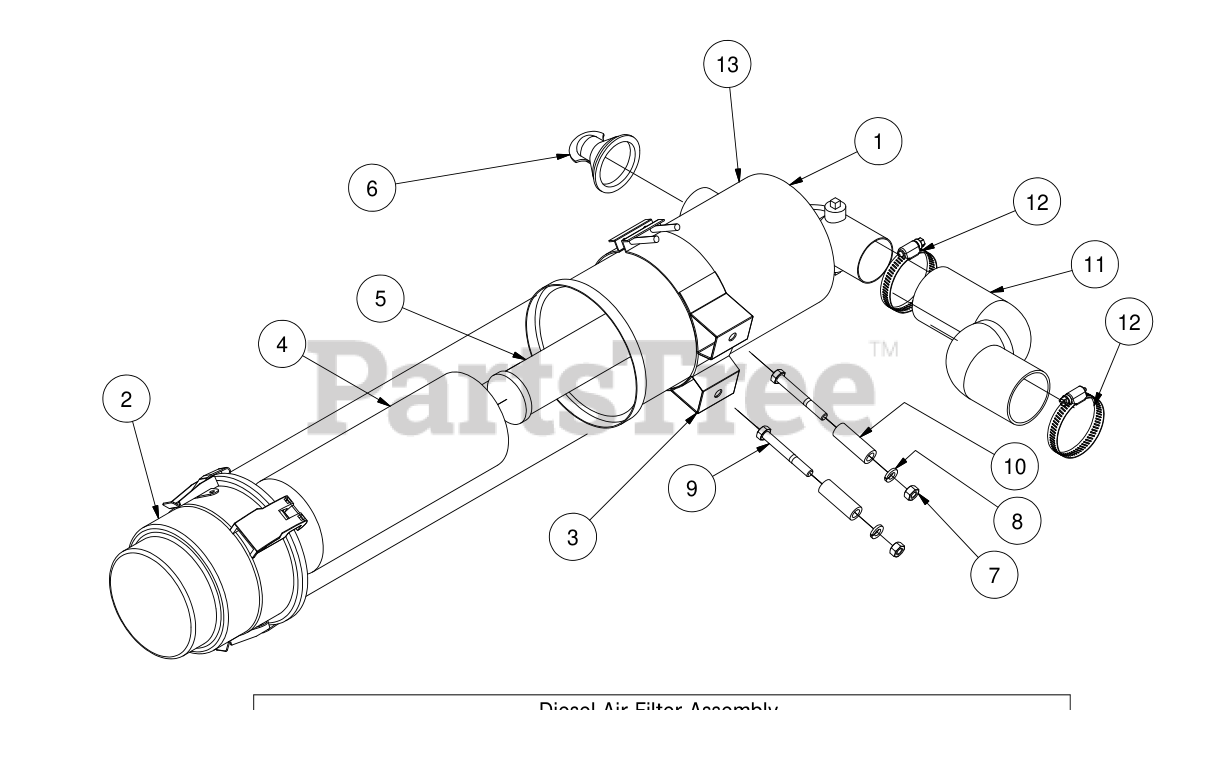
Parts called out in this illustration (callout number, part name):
1	Canister for All Diesel Models
2	Enginaire Air canister cap
3	Mounting Bracket For Diesel Air Filter
4	Diesel Air Filter- Outer
5	Diesel Air Filter- Inner
6	Debris Plug-Enginaire Filter
8	5/16" Lock Washer
9	5/16" x 2 1/2" Bolt
10	.378 x .625x 1.750 Spacer Zinc
11	Air Intake Hose-Diesel Air Filter Canister
12	2-1/2" Hose Clamp
13	Enginaire Canister VLR-Complete Assembly
